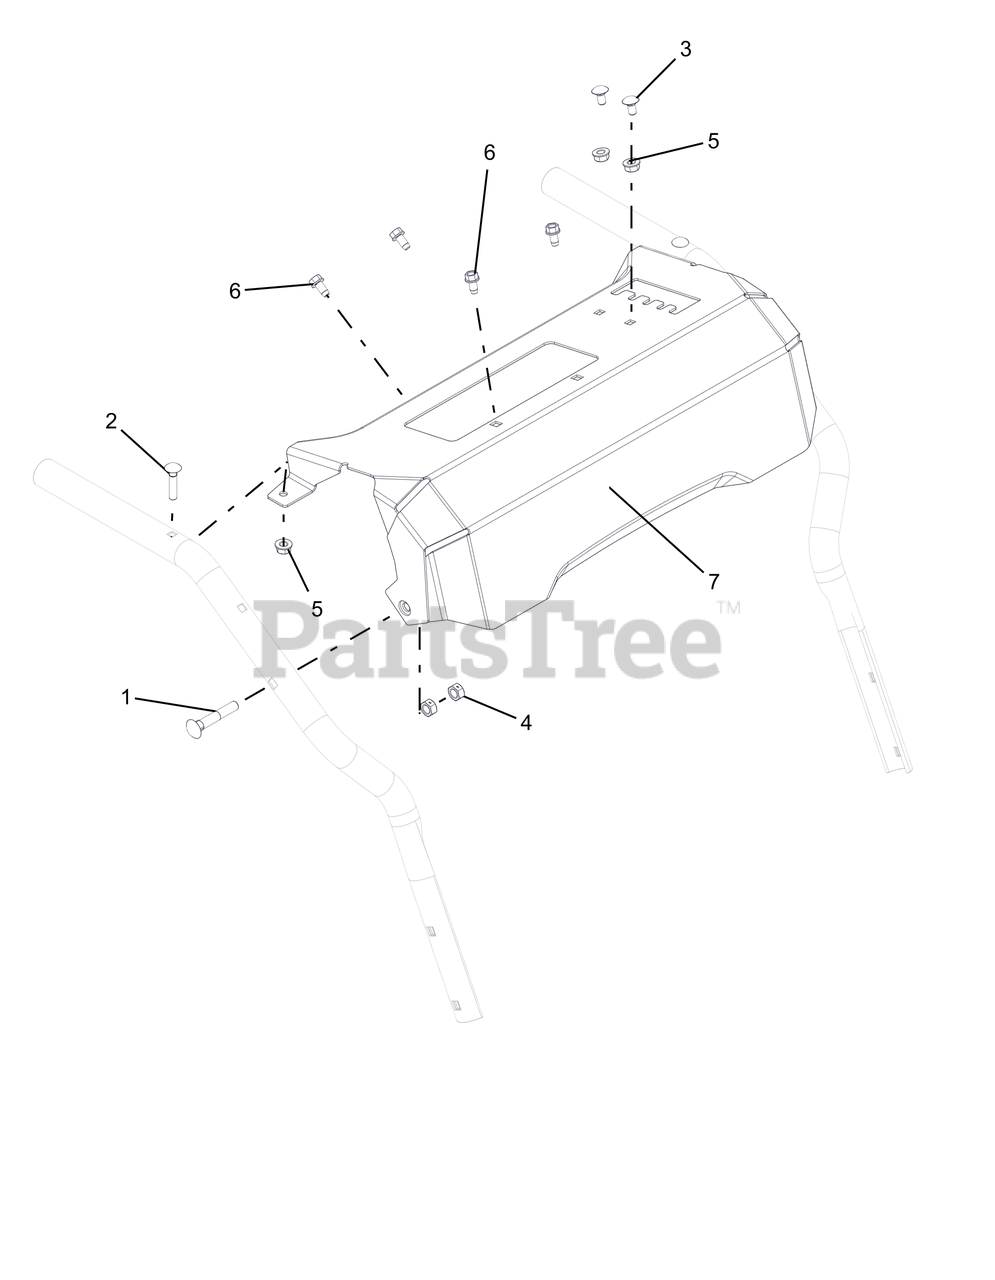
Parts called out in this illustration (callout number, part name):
1	BLT-RDHDXLSQNK .31-18X2.0 G5YZ
2	BLT-RDHDXLSQNK.25-20X1.25 G5ZC
3	@BLT-RDHDSQNK .25-20X.50 G5YZ
4	@NUT-LK-CTR .31-18 YWZC
5	@NUT-LK-TOP-FLG .25-20 YWZC
6	SCR-TAP .25-20X.50 HWH TR YWZ
7	CTRL PANEL W/DECAL SNO-TEK MAN
